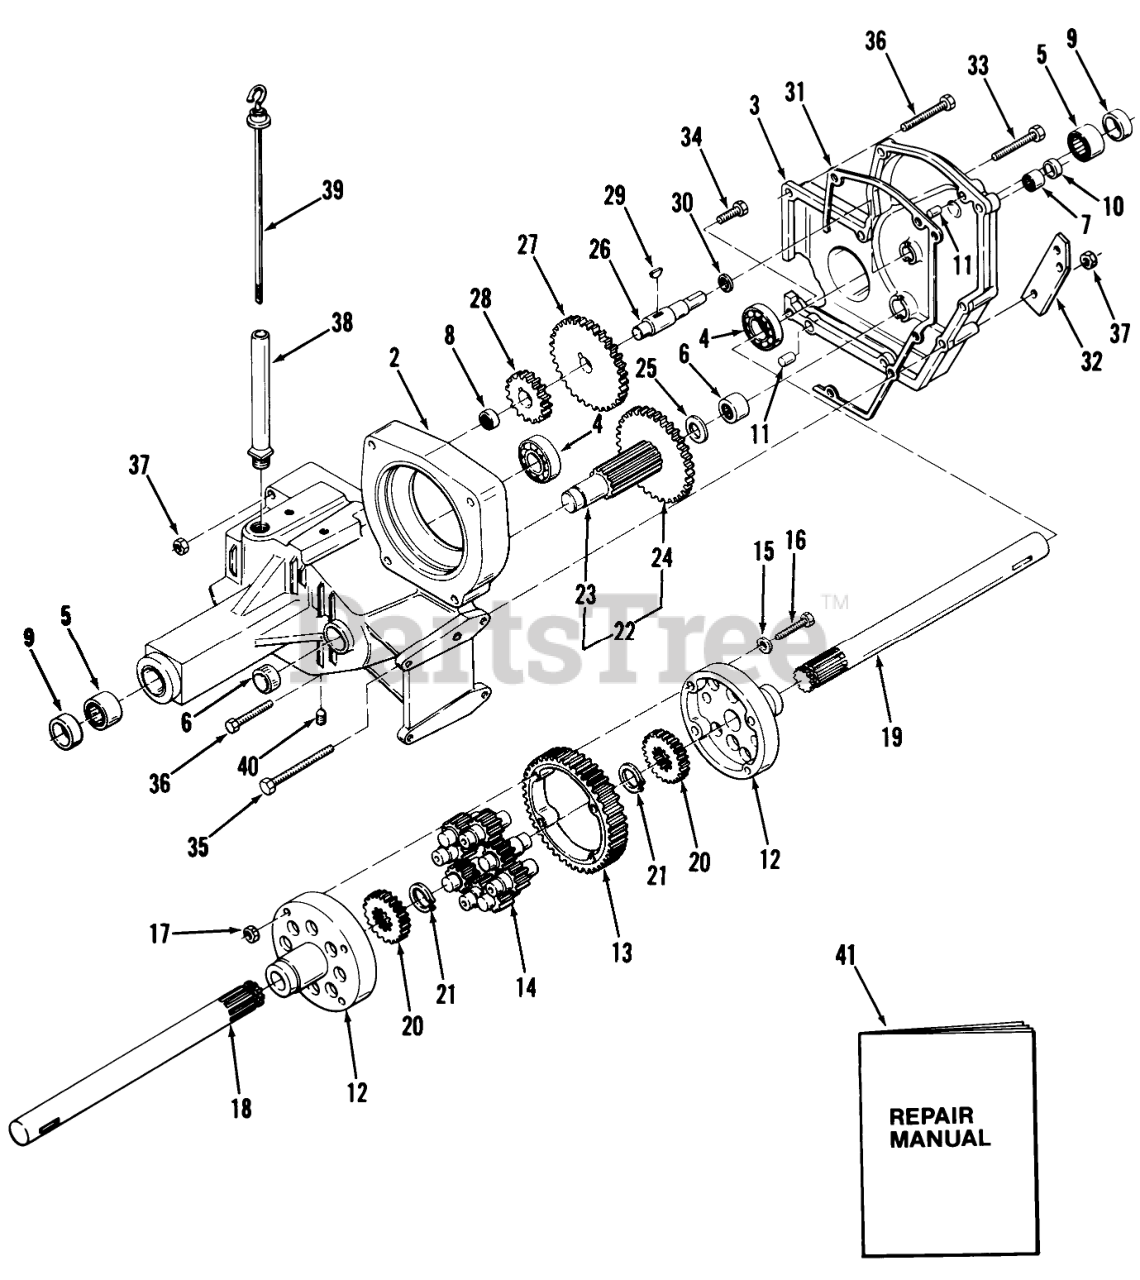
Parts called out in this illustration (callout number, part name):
1	Transaxle Complete
2	TRANS CASE RH
3	Case-Transaxle LH
4	BALL BRG 1 1/2 I.D.
5	BEARING
6	BEARING-NEEDLE
7	NEEDLE BEARING
8	BEARING-NEEDLE
9	SEAL-OIL
10	Seal
11	PIN-LOCATING
12	DIFFERENTIAL END CAP
13	GEAR-DIFFERENTIAL RING, 43T
14	GEAR-PINION, 11T
15	WASHER
16	BOLT-HEX
18	AXLE-REAR RH
19	AXLE-REAR LH
20	GEAR-AXLE DIFFERENTIAL
21	RING-SNAP
22	GEAR ASM
23	PINION SHAFT
25	WASHER-THRUST
26	SHAFT GEAR
27	Gear 44 Tooth
28	GEAR 22T
29	WOODRUFF KEY
30	Race Thrust
31	GASKET-TRANSMISSION
32	BRACKET-BRAKEB
33	Bolt
34	Bolt
35	H H C S
36	Screw-Hex. Hd.
37	Nut
38	NIPPLE-TRANS FILL
39	ASSY-DIPSTICK
40	PLUG 1/4 PIPE ALLEN
41	Repair Manual
